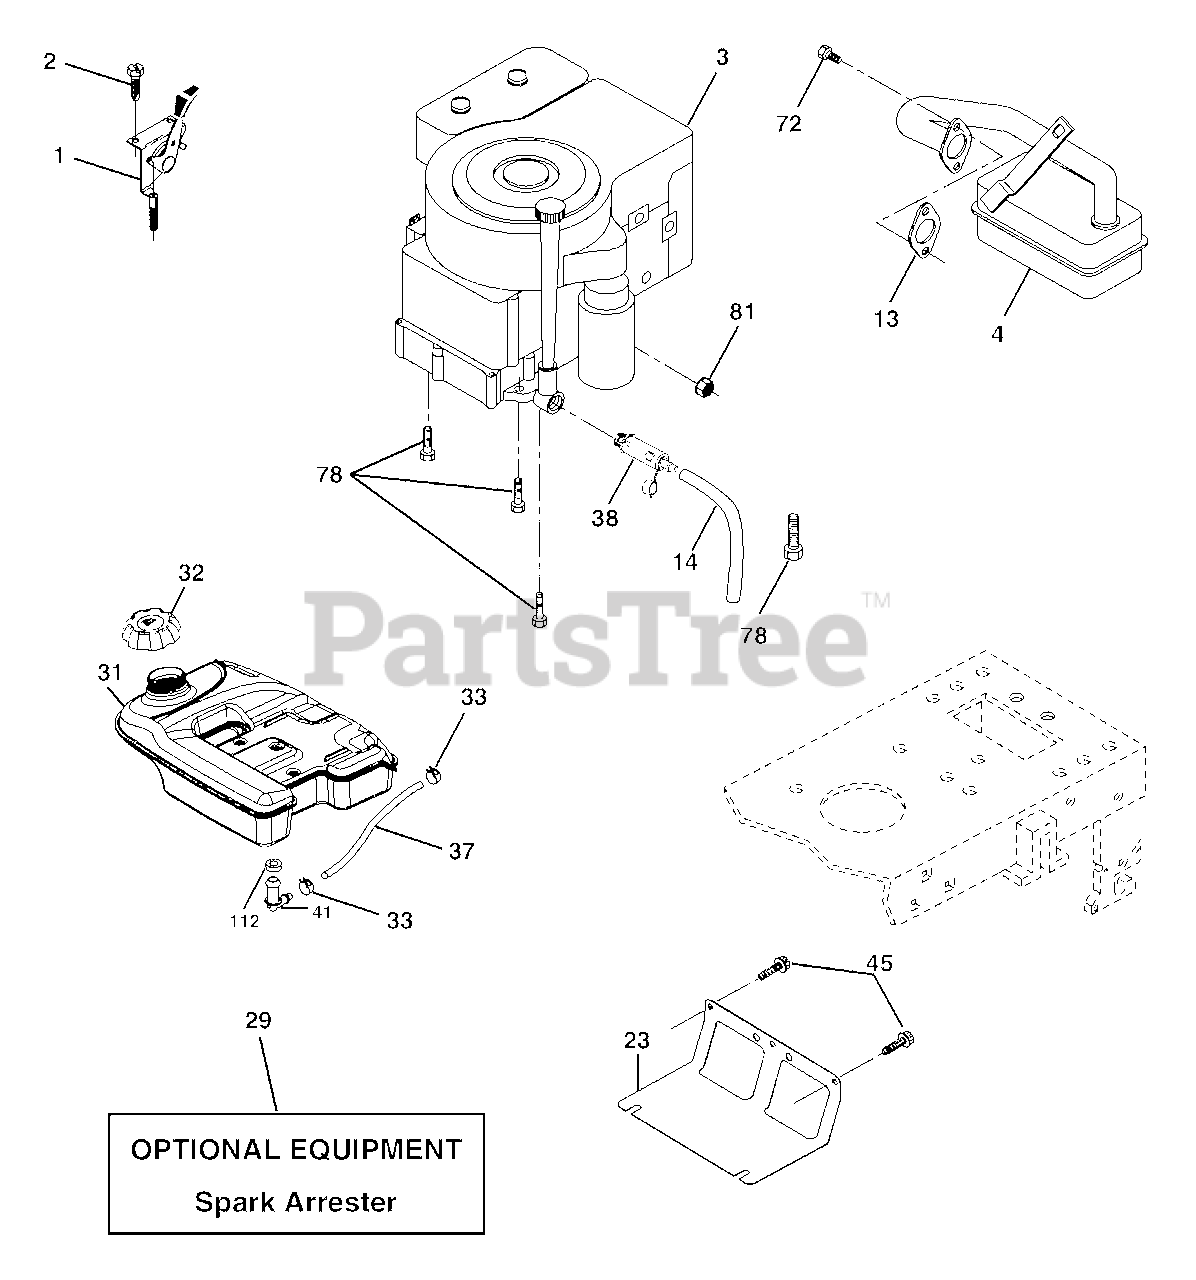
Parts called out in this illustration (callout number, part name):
1	Control Throttle/Choke
2	Screw Hwhd Hi-Lo #13-16 x 3/4
4	Muffler Asm Twin Lo-Tone
13	Muffler Gasket
14	Tube Drain oil
23	Shield Heat
29	Kit Spark Arrestor (Flat Scrn)
31	Tank Fuel
32	Cap Asm Fuel
33	Clamp Hose Black
37	Line Fuel
38	Plug Drain Oil Easy
41	Stem Tank Fuel
45	Screw Hexwsh Thdr 3/8-16 x 3/4
72	Screw 5/16-18 x 1
78	Screw 3/8-16 x 1-1/4
81	Nut Keps Hex 1/4-20 unc
112	Bushing
